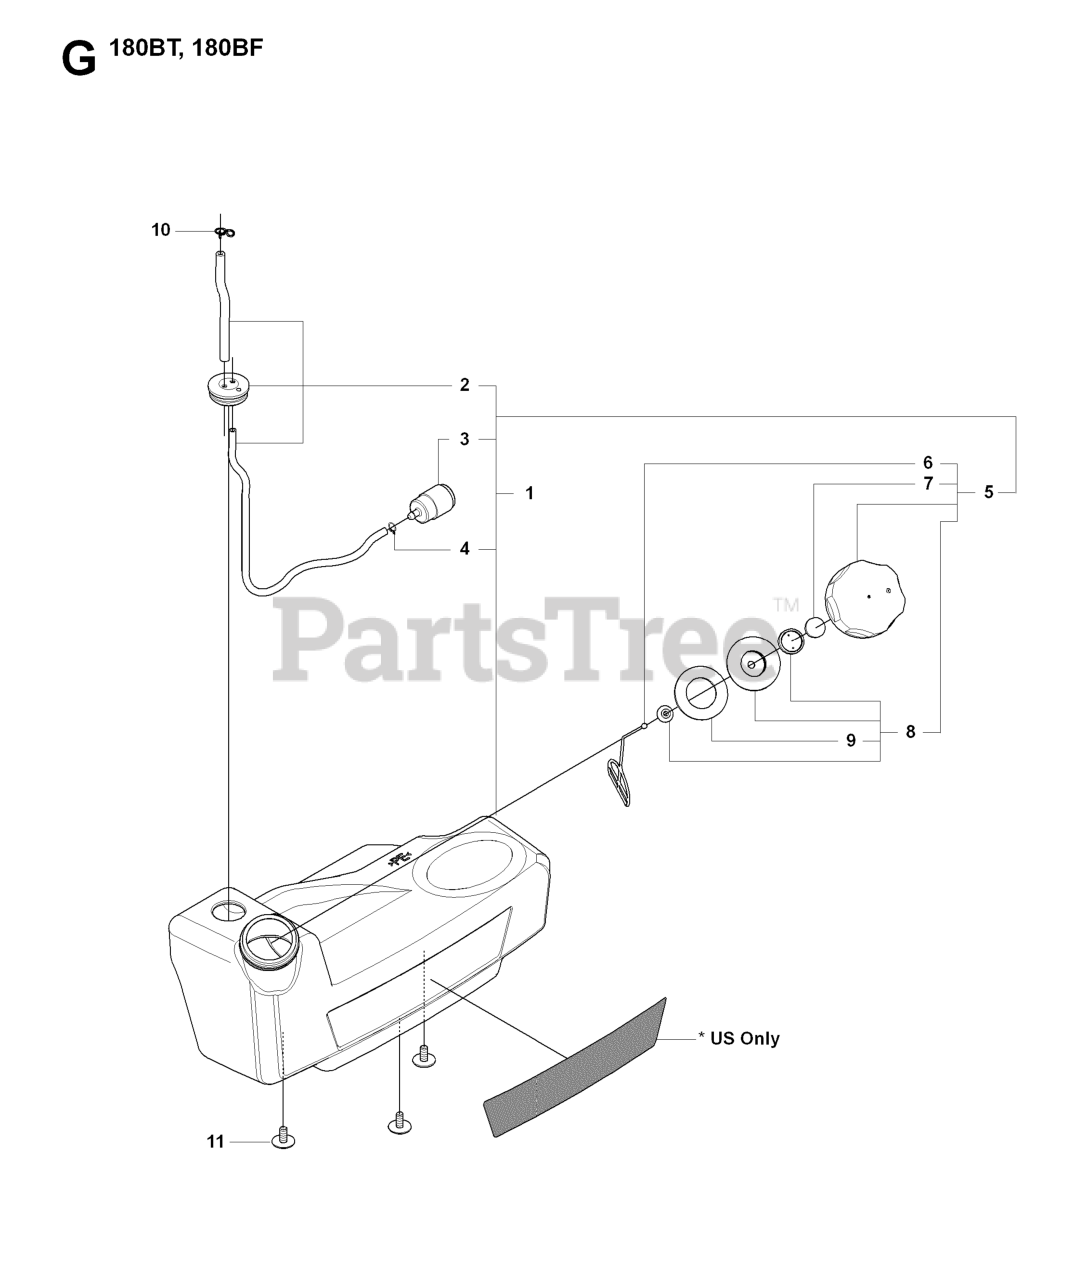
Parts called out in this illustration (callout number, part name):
2	PIPE C
3	FILTER
4	CLIP
5	ASSY FUEL CAP
7	FILTER
8	HOLDER-A
9	PACKING
10	CLIP
